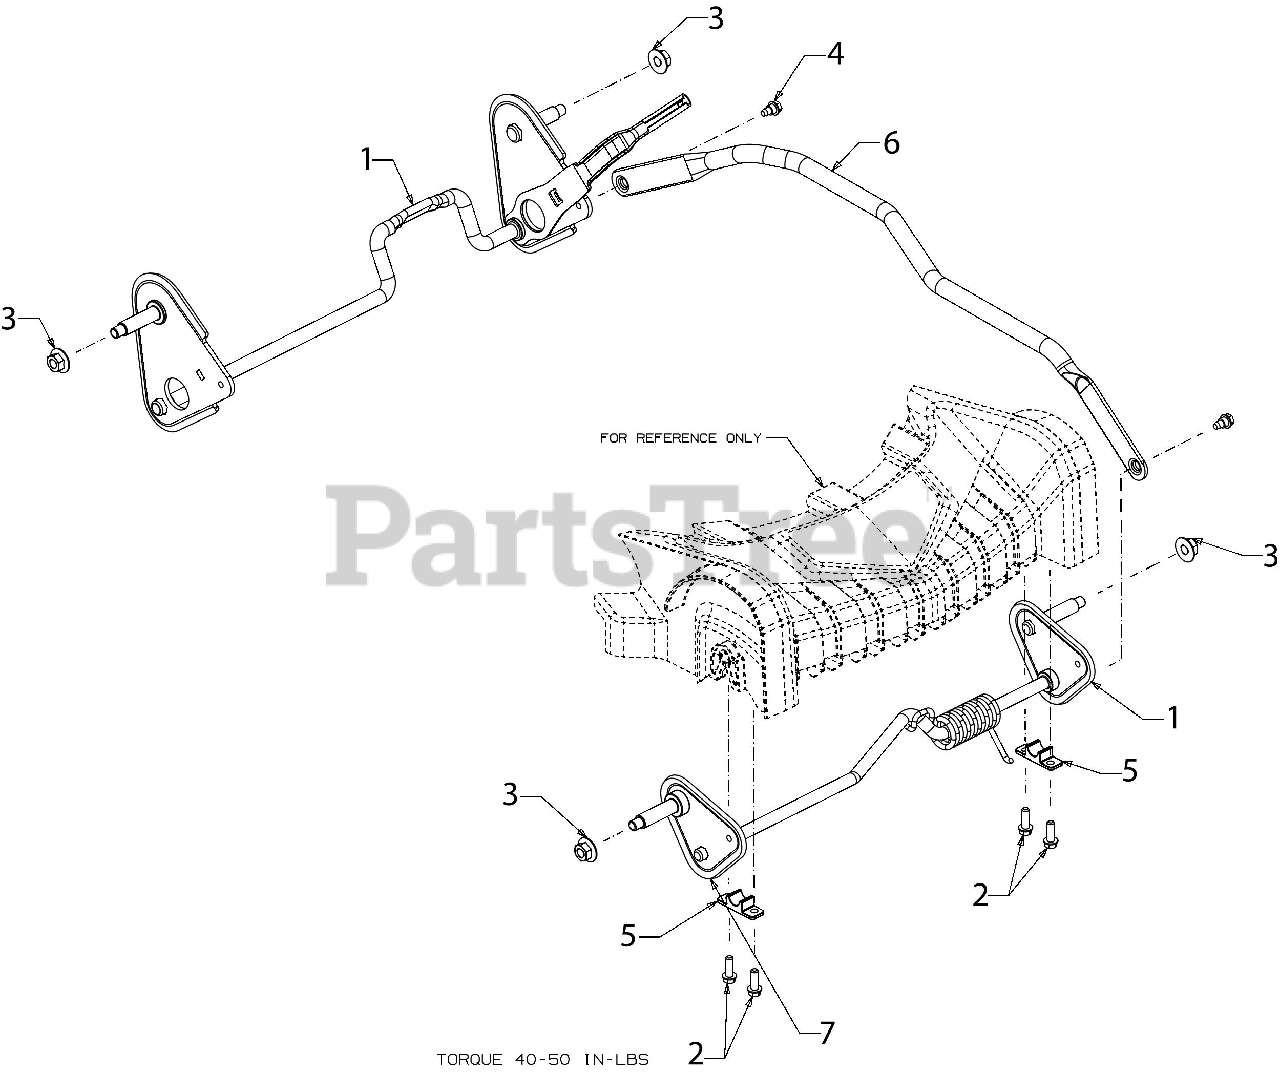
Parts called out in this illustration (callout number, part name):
1	HEIGHT AXLE ASSEMBLY
2	SCREW 1/4-15 X .750
3	FLANGE LOCK NUT
4	SHOULDER SCREW 1/4-20 X .50
5	BLOCK BUSHING
7	FRONT AXLE ASSEMBLY
